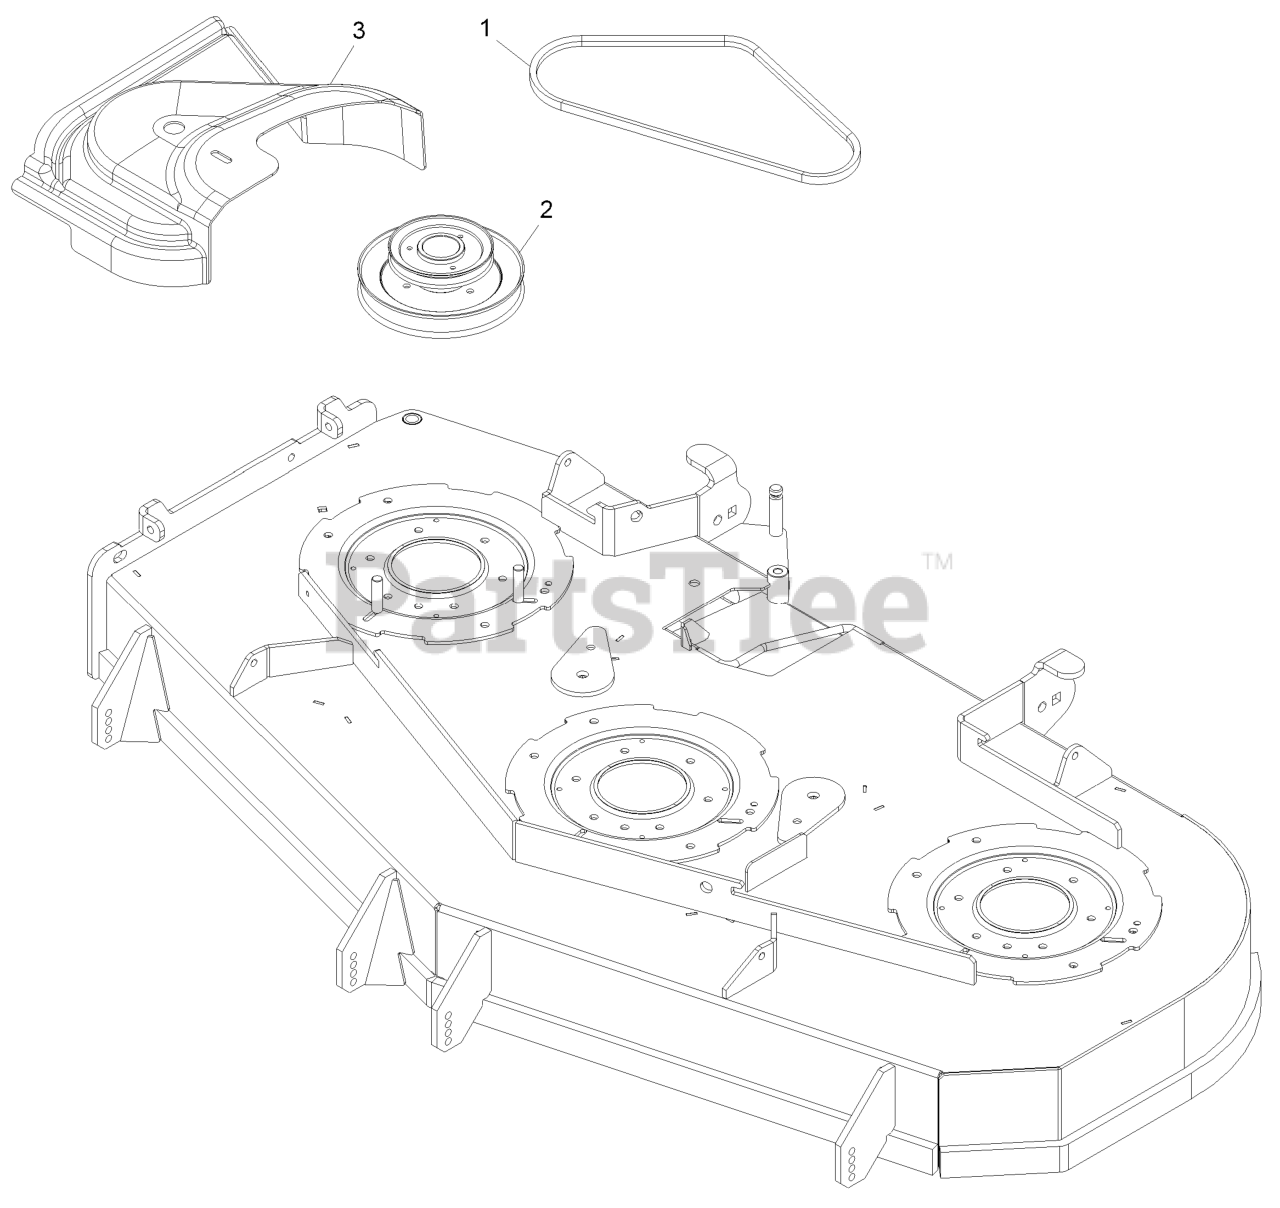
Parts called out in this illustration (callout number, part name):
1	BELT, BLOWER DRIVE 60
2	JACKSHAFT,UV DRIVE 604
3	COVER,BELT UV 60
